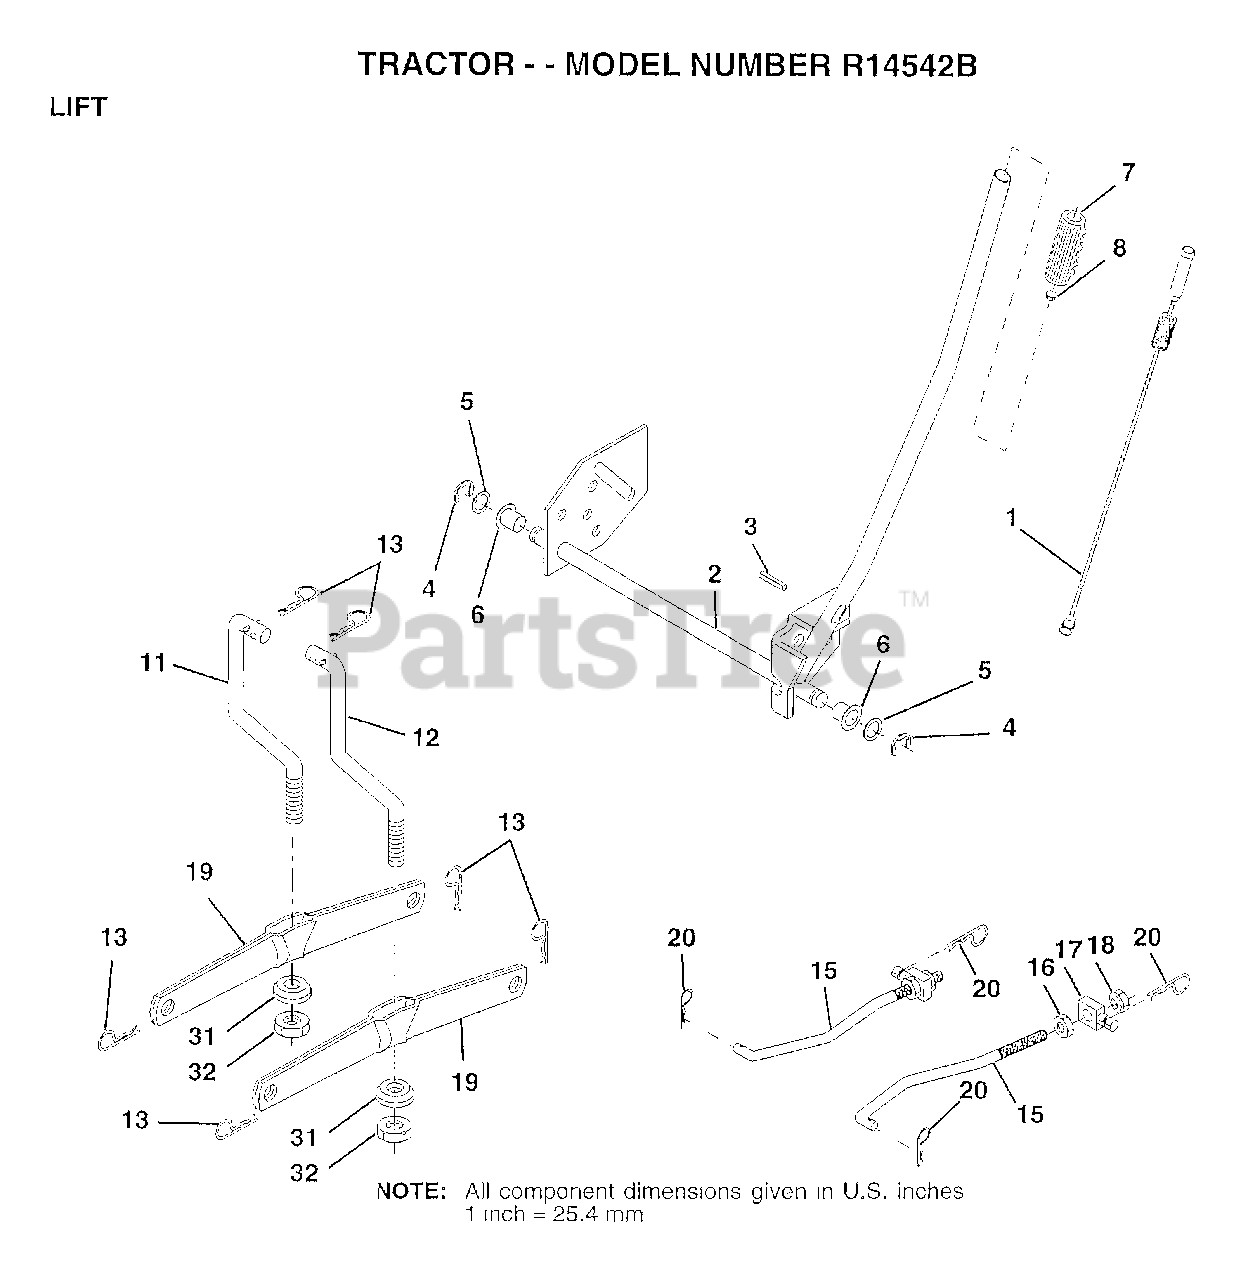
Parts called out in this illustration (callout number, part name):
1	WIRE.ASM.INNER.SP
2	"SHAFT AMS LIFT,RH"
3	PIN GROOVE
5	WASHER
6	NYLON BEARING
7	GRIP
15	LINK.FRONT
16	NUT
17	TRUNION
18	NUT.LK.W/WSH.1/2.
19	ARM SUSP REAR
20	RETAINER.SPRING
31	BEARING PVT LH
32	NUT.CROWNLOCK.3/8
